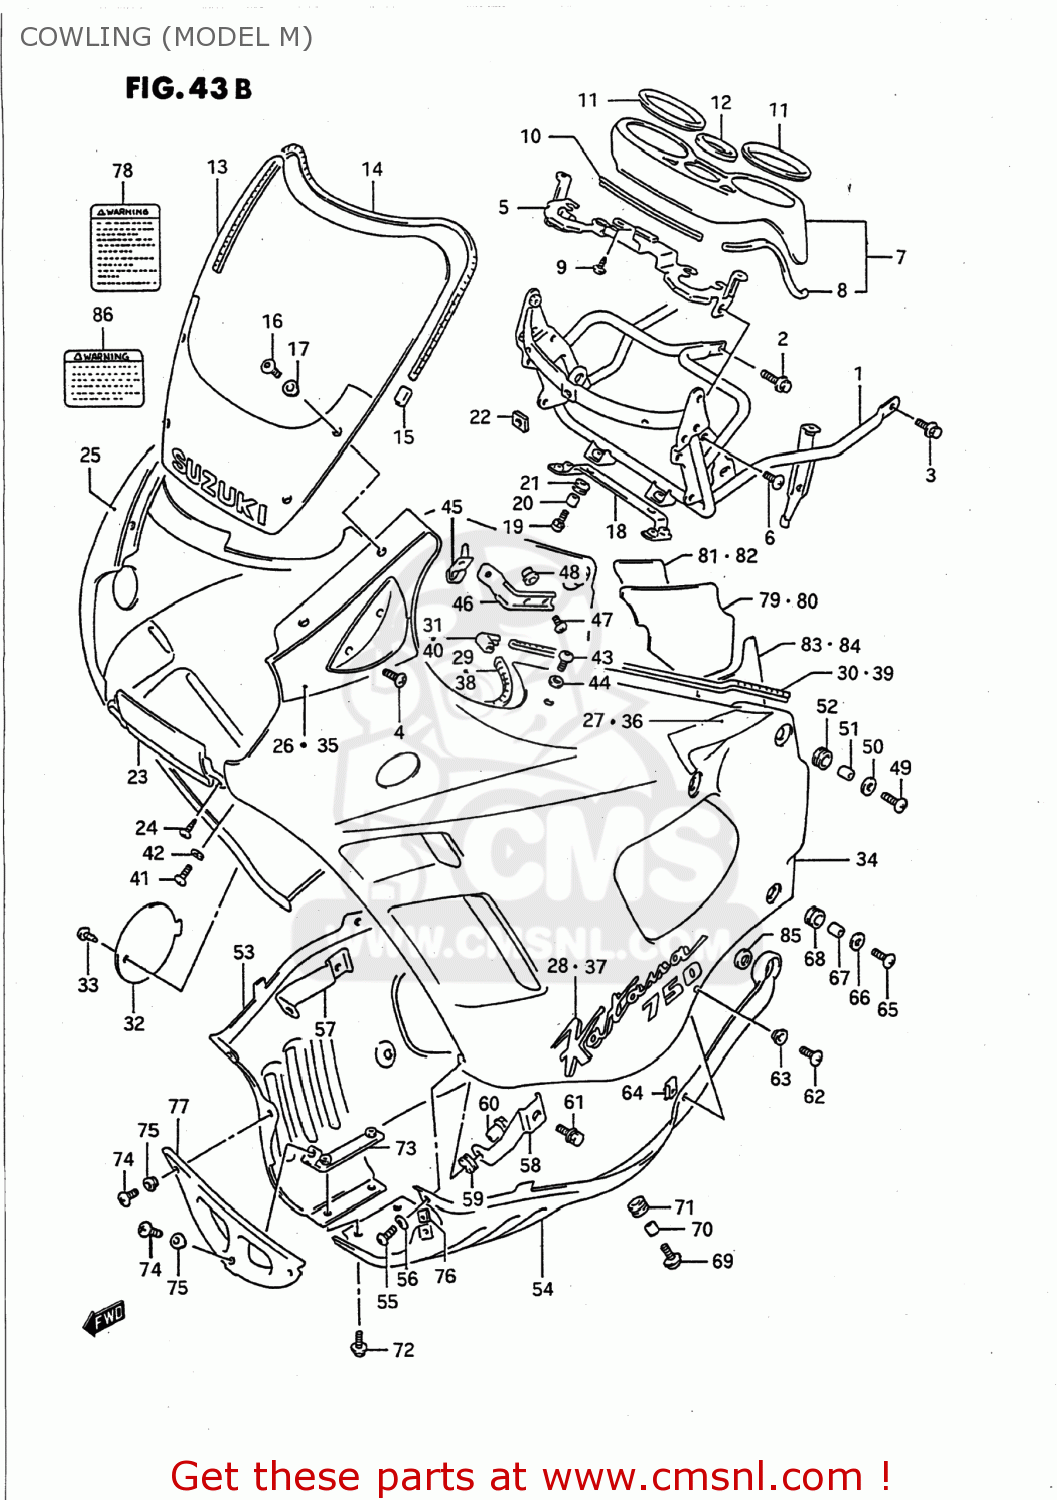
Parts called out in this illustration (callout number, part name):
1	BRACE,COWLING
2	BOLT
3	BOLT 6X12
4	SCREW 6X12
5	PLATE,METER FITING
6	SCREW 6X12
7	COVER COMP,METER
8	MOLDING
9	SCREW 5X8
10	MOLDING,METER COVER
11	CUSHION,SPEEDOMETER
12	CUSHION,FUEL METER
13	WINDOW,COWLING
14	MOLDING
15	CAP,MOLDING END
16	SCREW
17	WASHER(5.2X11X1)
18	PLATE,COWL CTR PANEL
19	SCREW(6X20)
20	SPACER (6,8X10X9.4)
21	CUSHION
22	CUSHION,SCREEN
23	PANEL,COWLING CTR
24	SCREW
25	COVER ASSEMBLY,COWLING,RIGHT
26	TAPE SET,COWLING SIDE
27	TAPE,COWLING,RIGHT
28	EMBLEM,COWLING SIDE,RIGHT
28A	COVER,COWLING METER SIDE,R
28B	COVER,COWLING METER,SIDE
28C	SCREW
29	MOLDING
30	MOLDING
31	JOINT,MOLDING END
32	LID,OIL
33	SCREW(6X16)
34	COVER ASSEMBLY,COWLING,LEFT
35	TAPE SET,COWLING SIDE
36	TAPE,COWLING,LEFT
37	EMBLEM,COWLING SIDE,LEFT
37A	COVER,COWLING METER SIDE,L
37B	COVER,COWLING METER,SIDE
37C	SCREW
38	MOLDING
39	MOLDING
40	JOINT,MOLDING END
41	SCREW(6X25)
42	WASHER(6.5X18X1.5)
43	SCREW(6X16)
44	WASHER(6.3X16X1.5)
45	BRACKET,COWLING UPR,R
46	BRACKET,COWLING UPR,L
47	SCREW(6X25)
48	NUT,COWLING SIDE BRKT
49	SCREW(6X25)
50	WASHER(6.5X18X1.5)
51	SPACER (6.1X9X9)
52	CUSHION
53	COVER,COWLING UNDER,R
54	COVER,COWLING UNDER,L
55	SCREW(6X30)
56	WASHER(6.5X18X1.5)
57	BRACKET,COWLING LWR,R
58	BRACKET,COWLING LWR,L
59	CUSHION
60	NUT,COWLING,FR
61	BOLT
62	SCREW(5X14)
63	WASHER(5.2X14X1.5)
64	NUT,HEADLAMP HOUSING,UPPER
65	SCREW(6X25)
66	WASHER(6.5X18X1.5)
67	SPACER(6.1X8X14.5)
68	CUSHION
69	SCREW(6X20)
70	SPACER (6.1X9X9)
71	CUSHION
72	SCREW, LOWER
73	BRACKET,FR UNDER COWL
74	SCREW
75	WASHER(5.2X14X1.5)
76	NUT,HEADLAMP HOUSING,UPPER
77	COVER,COWLING UNDER FR
78	LABEL (WARNING SCREEN)
79	BALANCER SHEET,COWLING,R
80	BALANCER SHEET,COWLING,L
81	CUSHION,COWLING,R
82	CUSHION,COWLING,L
83	SHEET,COWLING BALANCER,R
84	SHEET,COWLING BALANCER
85	CUSHION,UNDER COWLING RR
86	LABEL
